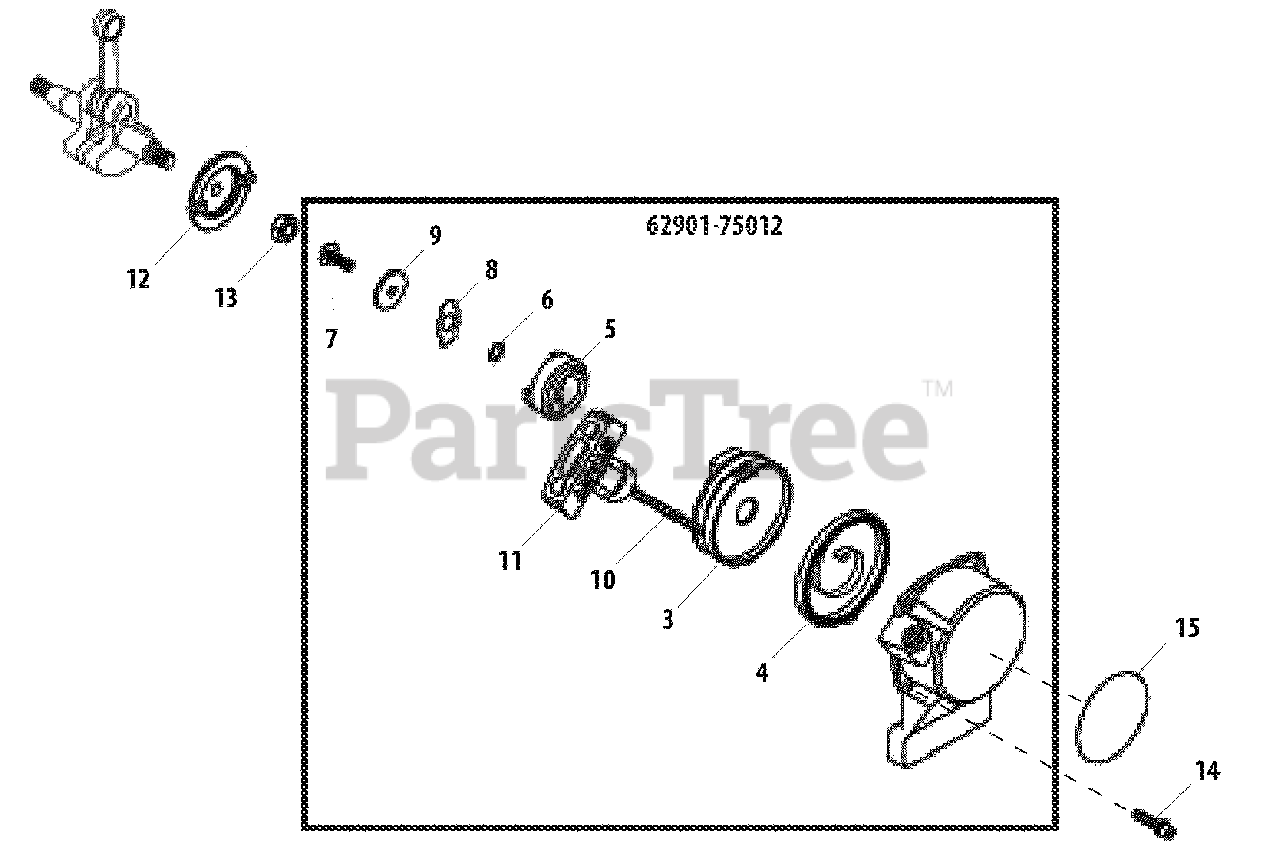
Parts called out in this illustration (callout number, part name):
3	REEL, ROPE
4	SPRING, REWIND
5	PAWL, STARTER
6	WASHER - SPRING
7	SCREW - 5
8	RETAINER
9	WASHER - 5
10	ROPE, STARTER
11	GRIP, STARTER
12	PAWL
13	NUT - 8
14	SCREW - 4X16
15	LABEL - C4
62901-75012	STARTER ASSY
